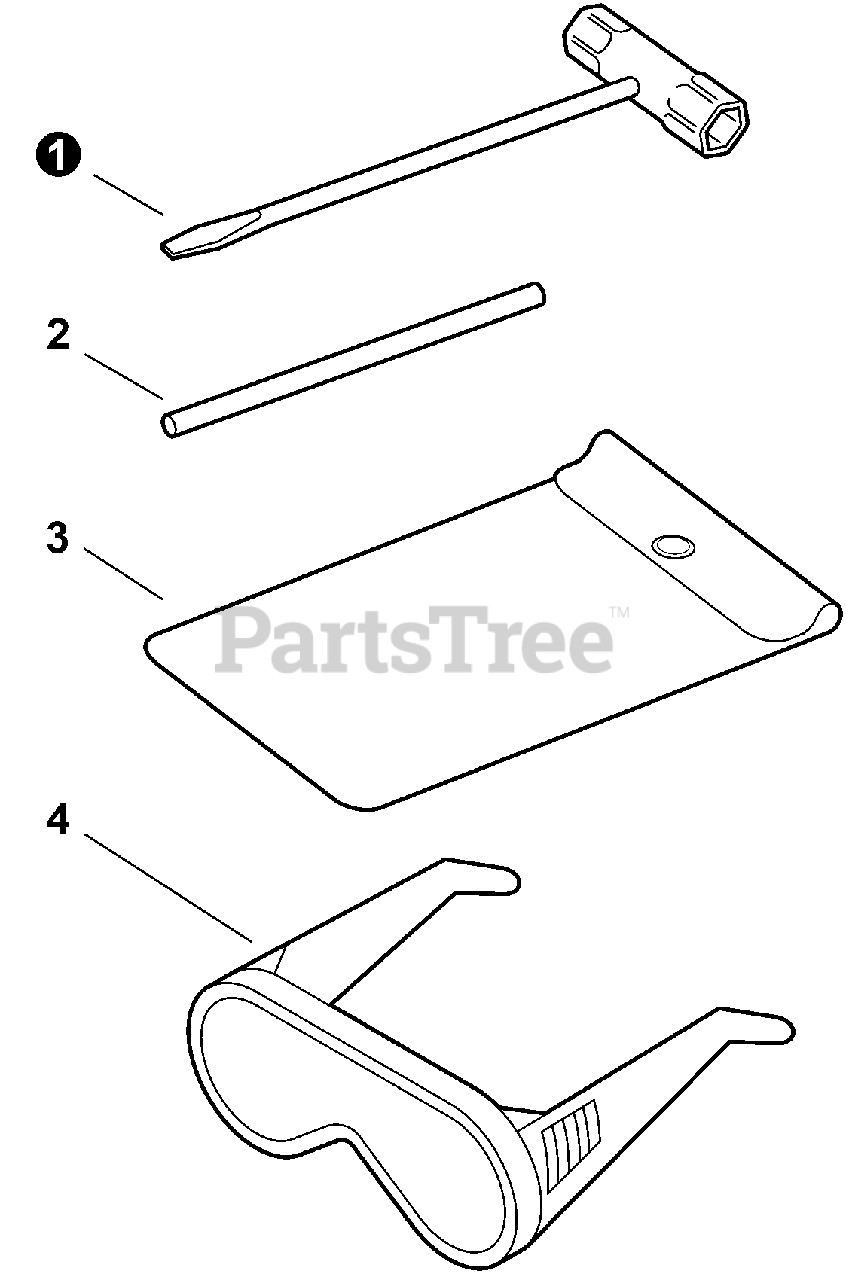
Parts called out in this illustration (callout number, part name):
1	T-WRENCH - 10×19mm
2	ROD, LOCKING - 5×120mm
3	BAG,TOOL
4	GOGGLES
